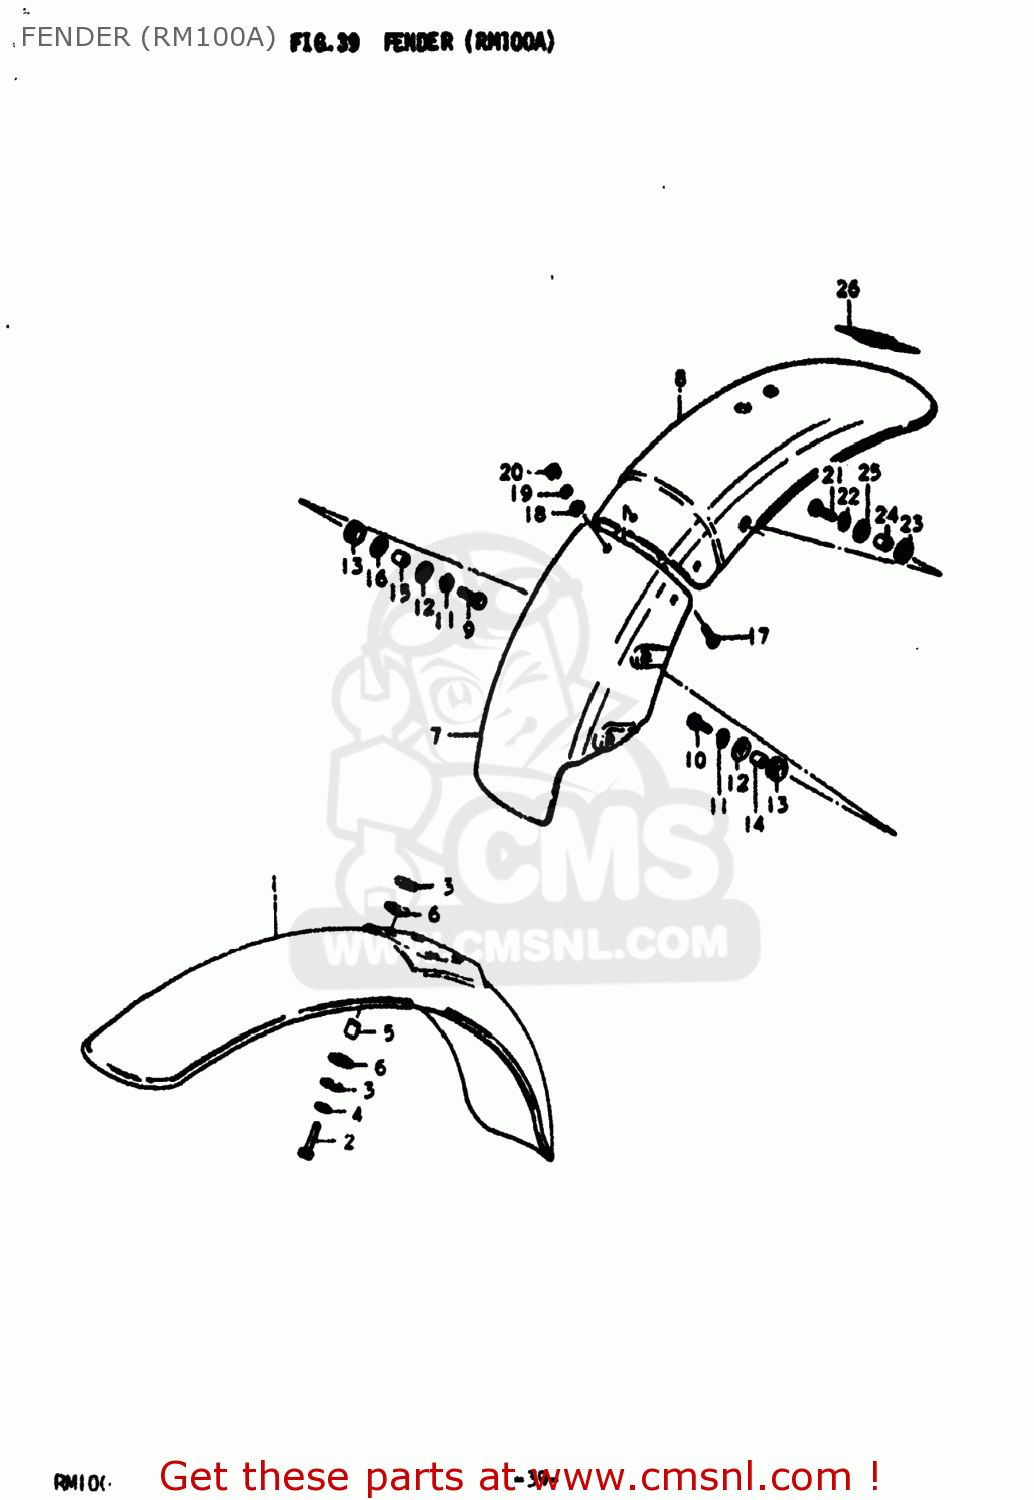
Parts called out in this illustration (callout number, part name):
1	FENDER,FRONT
2	BOLT
3	WASHER (6.5X20X1.2)
4	LOCK WASHER
5	SPACER (6.8X10X10)
6	CUSHION
7	FENDER,REAR
8	FENDER,REAR
9	BOLT
10	BOLT
11	LOCK WASHER
12	WASHER (6.5X20X1.2)
13	CUSHION
14	SPACER(6.1X9X7.5)
15	SPACER (6.1X8X12)
16	CUSHION
17	SCREW
18	WASHER
19	LOCK WASHER
20	NUT
21	BOLT(6X18)
22	LOCK WASHER
23	CUSHION
24	SPACER(6.1X9X7.5)
25	WASHER (6.5X20X1.2)
